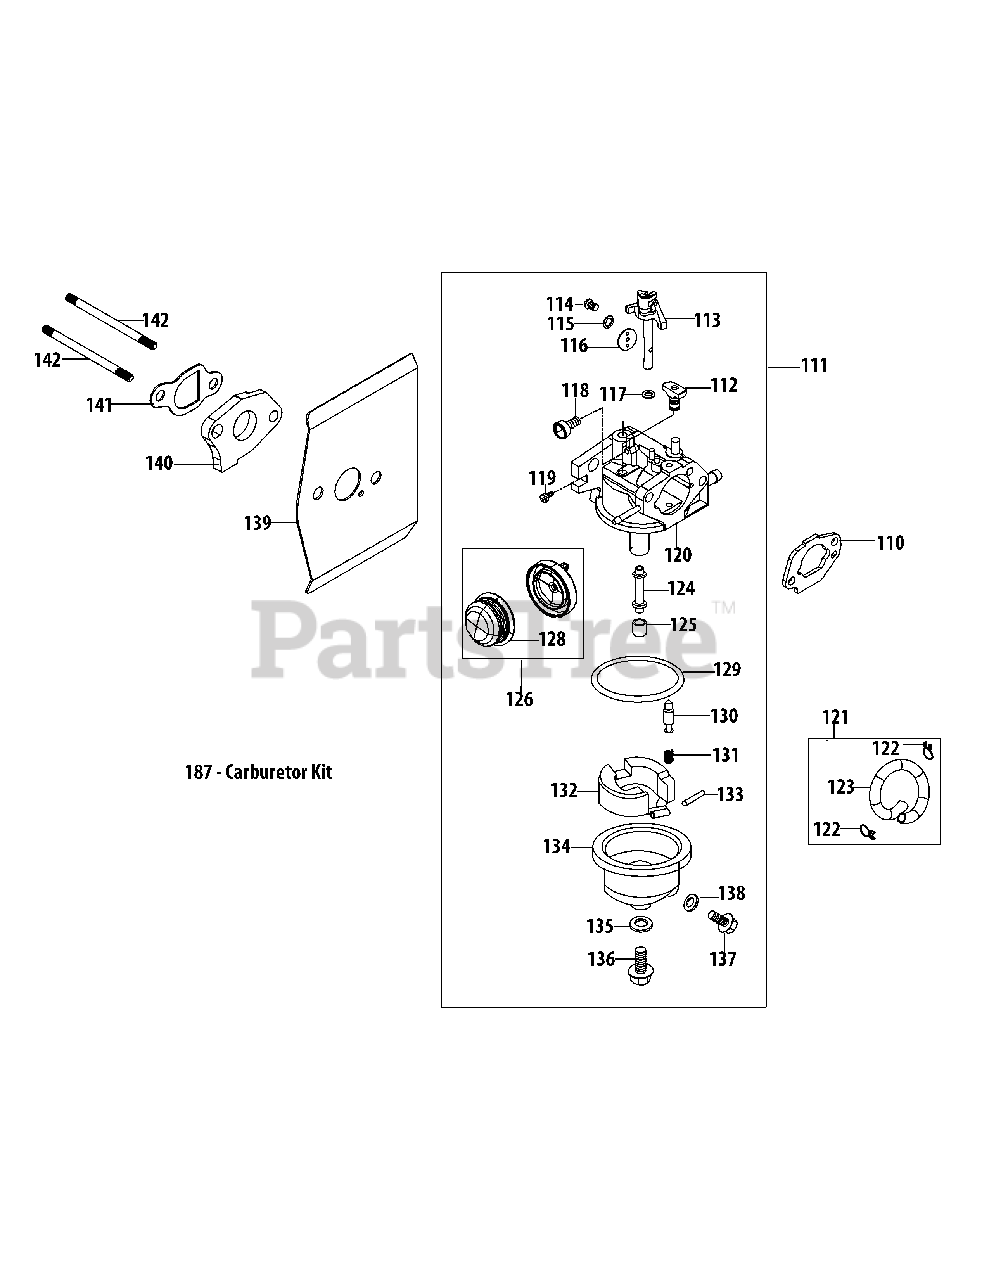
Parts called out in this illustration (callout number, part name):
110	Carburetor Gasket Plate
111	Carburetor Assembly
112	Idle Jet Assembly
113	Throttle Shaft
114	Screw M3X5
115	Throttle Plate Lock Washer
116	Throttle Plate
117	Throttle Shaft Fiber O-Ring
118	Idle Speed Adjusting Screw
119	Idle Mixture Screw
120	Carburetor Body
121	Primer Hose Assembly
122	Primer Hose Clamp
123	Primer Hose
124	Emulsion Tube
125	Main Jet
126	Primer Assembly
127	Primer Base
128	Primer Bulb
129	Fuel Bowl O-Ring
130	Needle Valve
131	Needle Valve Spring
132	Float
133	Float Pin
134	Fuel Bowl
135	Fuel Bowl Gasket
136	Fuel Bowl Mounting Bolt
137	Fuel Drain Plug
138	Fuel Drain Plug Gasket
139	Carburetor Gasket
140	Carburetor Insulator
141	Carburetor Insulator Gasket
142	Carb Stud M6X92
187	Carburetor Kit -Major
